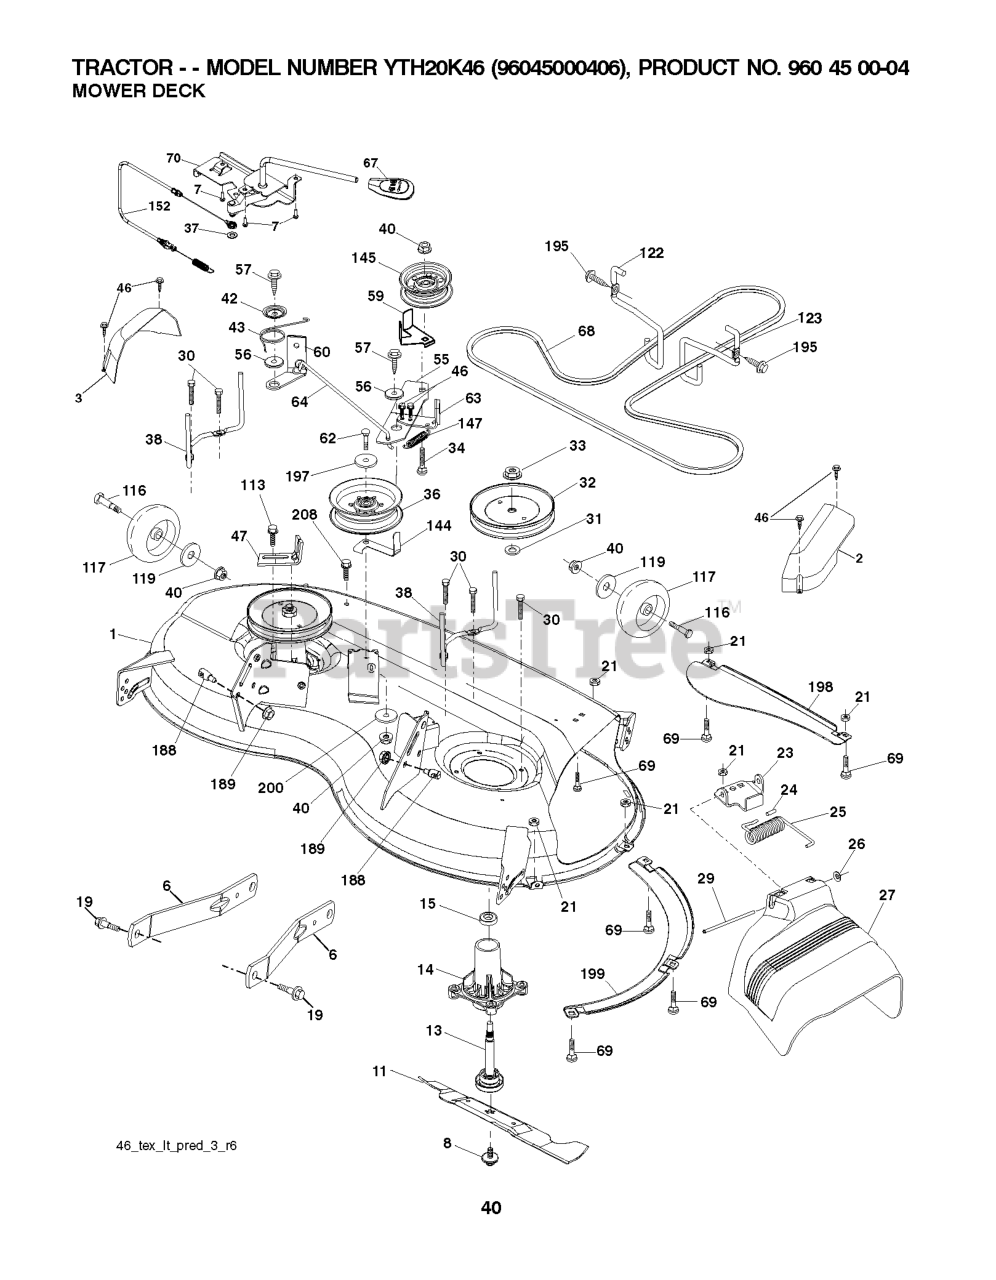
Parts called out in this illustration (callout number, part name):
1	DECK.WELDMENT.46"
2	COVER.MANDREL.RH.46"
3	COVER.MANDREL.LH.46"
6	ARM.SUSPENSION.MOWER.R
7	SCREW.#10 X 0.750.BOS
8	BOLT.WASHER.ASM.7/16-2
11	BLADE.MOWER.46".HI.LIFT
13	SHAFT.ASM.MDRL.N/GREASE.38
14	RP.HOUSING.MANDREL.4PT.
19	BOLT.SHOULDER
21	LOCKNUT
23	BRKT.DEFLECTOR.38"2005+
24	CAP-SLEEVE LT
25	SPRING.TORSION.DEFLECT
26	NUT PUSH M
27	SHIELD.DEFLECTOR.MOWER.46"BLAC
29	ROD.HINGE
30	SCREW, WASHER HEAD
31	WASHER.SPACER.MANDREL
32	PULLEY.MANDREL.5.438.PD
33	NUT.FLANGE.LOCK.TOP
34	BOLT.3/8-16X1.50
36	PULLEY.IDLER.2006
37	WASHER
38	KEEPER.BELT.LH.MANDREL
40	NUT LOCK FLG 3/8-16 UNC
42	SPRING.TORSION.BRAKE
43	SRPING.TORSION.RETAINE
46	SCREW.1/4-20X5/8
47	BRKT.CLUTCH.CABLE
55	IDLER.ARM
56	SPACER.RETAINER
57	SCREW 3/8-16X1
59	GUARD, BELT
60	ARM BRAKE MOWER RH 38"
62	BOLT-HEX EAK
63	ARM BRAKE MOWER
64	LINKAGE BRAKE
67	HANDLE.CLUTCH.CABLE.LT
68	V-BELT
69	BOLT
70	CLUTCH.ASM.CABLE.HUSQ.TEX
113	BOLT.5/16HEX.WHS.HD
116	BOLT.SHOULDER.3/8-16X3-5/8.
117	RP WHEEL. GUAGE RALLY
119	WASHER
122	KEEPER BELT ENGINE LH
123	KEEPER BELT RH
144	KEEPER.BELT.MOWER
145	PULLEY.IDLER.48"PRIMARY
147	SPRING RETURN
152	CABLE CLUTCH MANUAL W/SPR.
188	STUD.FASTNER.W/ANTI-ROTATE
189	NUT LOCK HEX FLANGE 5/16-18
195	SCREW, 3/8-16X3/4
197	WASHER
198	BAFFLE CENTER FRONT
199	BAFFLE FRONT RH
200	WASHER.13/32 X 1 X 1/2.11GUARD
208	SCREW 3/8-16X1/2
